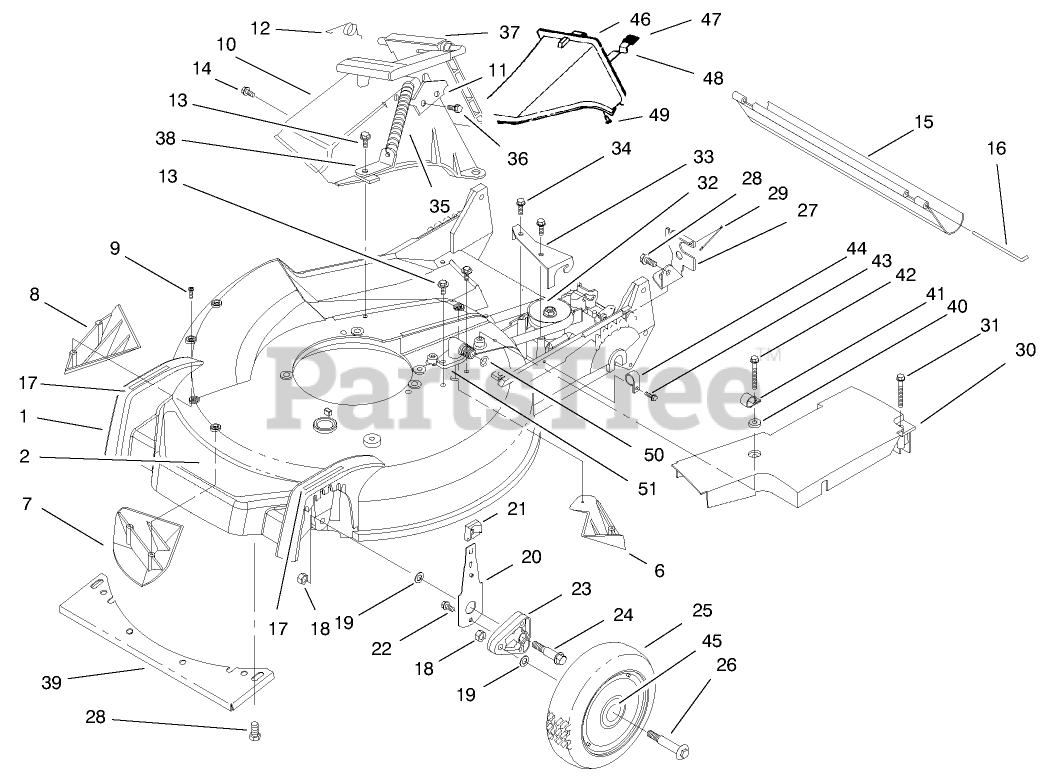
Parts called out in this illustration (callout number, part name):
6	KICKER-REAR
7	KICKER-FRONT
8	KICKER-RH
9	SCREW-PPH
10	TUNNEL-DISCHARGE
11	LATCH-PLATE
12	RETAINER-DOOR
13	SCREW-HWH
14	SCREW AND WASHER ASM
16	ROD-SHIELD
18	NUT-LOCK
19	WASHER
20	FRONT SPRING ARM ASM
21	KNOB-ARM
22	SCREW-HWH
24	BOLT-SHOULDER
28	SCREW-HWHTF
29	RETAINER-CABLE
31	SCREW-HWH
32	GEARCASE ASM
34	SCREW-HWHTF
35	SPRING-DOOR
36	SCREW-PLASTITE
37	DISCHARGE DOOR ASM
38	BRACKET-SPRING
40	WASHER
41	CLAMP-CABLE
42	SCREW-SPECIAL
43	SCREW-HWH
44	CLAMP-CABLE
45	BUSHING
46	DISCHARGE PLUG ASM
47	GRIP-LATCH
48	LATCH-PLUG, DISCHARGE
49	RIVET-HEAD, FLAT
50	O-RING
